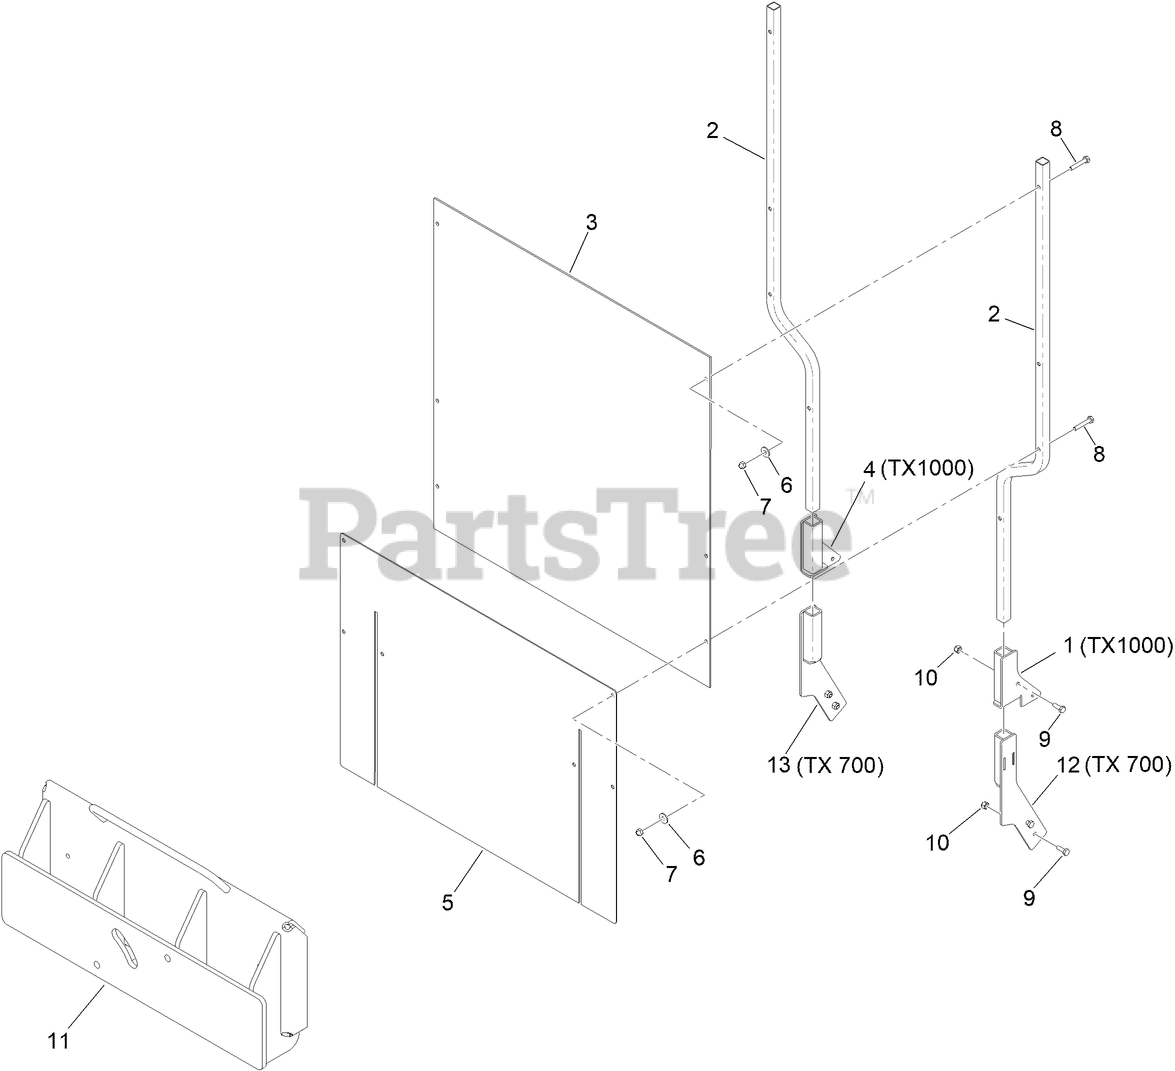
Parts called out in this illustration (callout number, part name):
1	BRACKET-SUPPORT, LH
2	SUPPORT-TUBE, SHIELD
3	SHIELD-LEXAN
4	BRACKET-SUPPORT, RH
5	SKIRT-PROTECTOR
6	WASHER-FLAT
7	NUT-HEX
8	SCREW-HH
9	SCREW-HH
10	NUT-LOCK, NI
11	PLATE-ATTACH, QUICK
12	BRACKET-SUPPORT LH
13	BRACKET-SUPPORT RH
